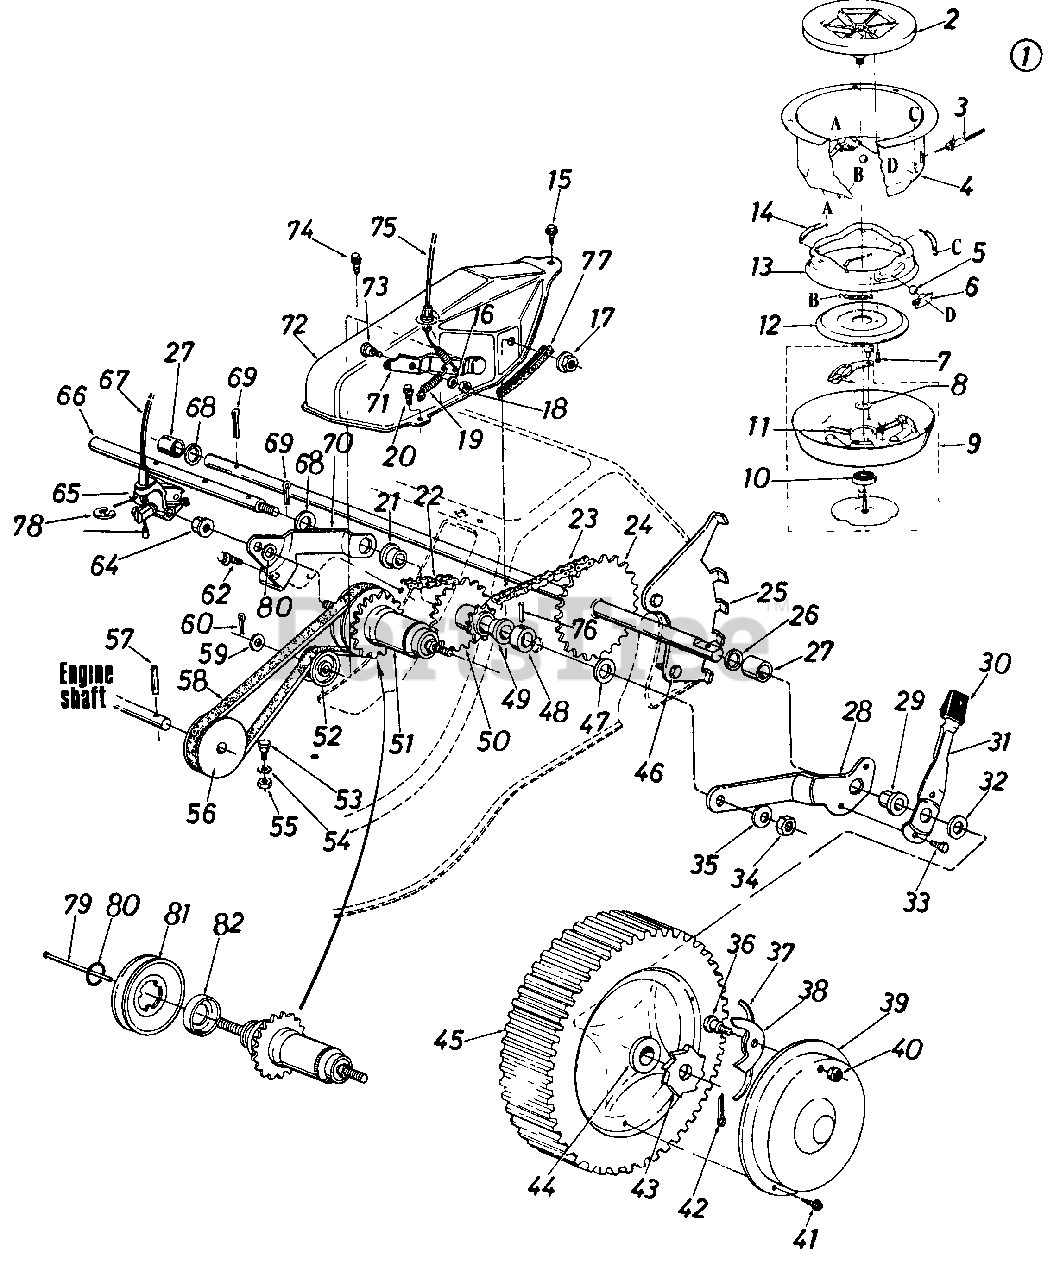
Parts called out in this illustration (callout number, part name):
1	Blade/Brake Clutch Ass'y.
3	BBC-Clutch Cable 46"
4	Clutch Housing
5	Steel Ball .500" Dia.
7	Hex Wash. TT-Tap Cl-Scr. 1/4-20 x .75" Lg.
8	Fl-Wash. .690" I.D. x 1.060" O.D.
9	Clutch Blade Hsg. Ass'y.
10	Ball Brg 669" I.D. x 1.574 O.D.
11	Compression Spring .32" O.D. x 2.00" Lg.
12	Clutching Cone
13	Brake Cup Cone
14	Extension Spring 1.75" Lg.
15	Hex Drilling Scr. #10 x .50"
16	L-Wash. 1/4" I.D.*
17	Hex Nut 3/8-24 Thd.
18	Hex Nut 1/4-20 Thd.*
19	Extension Spring 1.12" Lg.
20	Hex Wash. S-Tap Scr. 1/4-20 x .50" Lg.
21	Flg. Brg. .506" I.D. Plastic
22	#48 Chain 1/2" Pitch x 38 Links (Endless)
23	#48 Chain 1/2" Pitch x 32 Links (Endless)
24	Rear Shaft Ass'y. 20.75"
25	Index Plate Rear L.H.
26	Fl-Wash. .510" I.D. x 1.0"
27	Spacer .740" I.D.
28	Pivot Brkt. L.H.
29	Hex Flange Brg. .506" I.D. Plastic
30	Spring Lever Knob
31	Spring Lever
32	Fl-Wash. .531" I.D. x .930"
33	Hex B-Tap Scr. 1/4 x .38"
34	Hex Jam Nut 3/8-16 Thd.
35	Bell-Wash. .400" I.D. x .88"
36	Shld. Bolt .342" Dia. x .268
37	Spring Nylon
38	Pawl
40	Hex Ins. L-Nut 1/4-20 Thd.
41	Pan Hd. Tap Scr. #12 x .50" Lg.*
42	Cotter Pin 1/8" Dia. x 1.0"*
43	Ratchet Wheel 1.62" O.D.
44	Fl-Ball Brg. 1/2" I.D.
45	Wheel Ass'y. Comp. 8 x 1 .75
46	Hex L-Wash. Hd. AB-Tap Scr. 1/4 x .62" Lg.
47	Bell-Wash. .40" I.D. x 1.13"
48	Spacer.505" I.D.
49	Flg. Brg. .506" I.D. Plastic
50	9 and 21 Tooth Sprocket Ass'y.
51	Shimano 3-Sp. Hub w/ 18 0 Tooth Sprocket
52	Fl-Idler Plastic 1.62" Dia.
53	Shld. Bolt .437" Dia. x .180
54	L-Wash. 5/16" I.D.
55	Hex Nut 5/16-18 Thd.*
56	1/2" "V"Engine Pulley .50" I.D. x 2.80" O.D.
57	Spring Pin Spir. 3/16" Dia. x 1.50" Lg.
58	"V"Belt 1/2" X 26.0" Lg.
59	Fl-Wash. .531" I.D. x .930"
60	Cotter Pin 1/8" Dia. x 1.01"
62	Hex Wash. Hd. Tap Scr. 5/16-18 x .75" Lg.
64	Hex Nut 3/8-24 Thd.
65	Shimano 3-Sp. Shift Bell Crank
66	Pulley Shaft 10" Lg.
67	Shimano 3-Sp. Solid Shift Cable
68	Fl-Wash. .531" I.D. x .930"
69	Cotter Pin 3/32" Dia. x 1.0"*
70	3-Sp. Hub Bracket
71	Idler Bracket Ass'y.
72	3-Sp. Belt Cover
73	Shld. Bolt .375" Dia. x .181
74	Hex TT-Tap Scr. 1/4-20 x .75" Lg.
75	S.P. Cable 53" Lg. Blue
76	Spring Pin Spir. 3/16" Dia. x 1.0" Lg.
78	Snap Ring
79	Shifting Pin
80	Pulley Snap Ring
81	3/2" V-Pulley 1.375" I.D. x 3.25" O.D.
82	Shimano 3-Sp. Dust Cover
